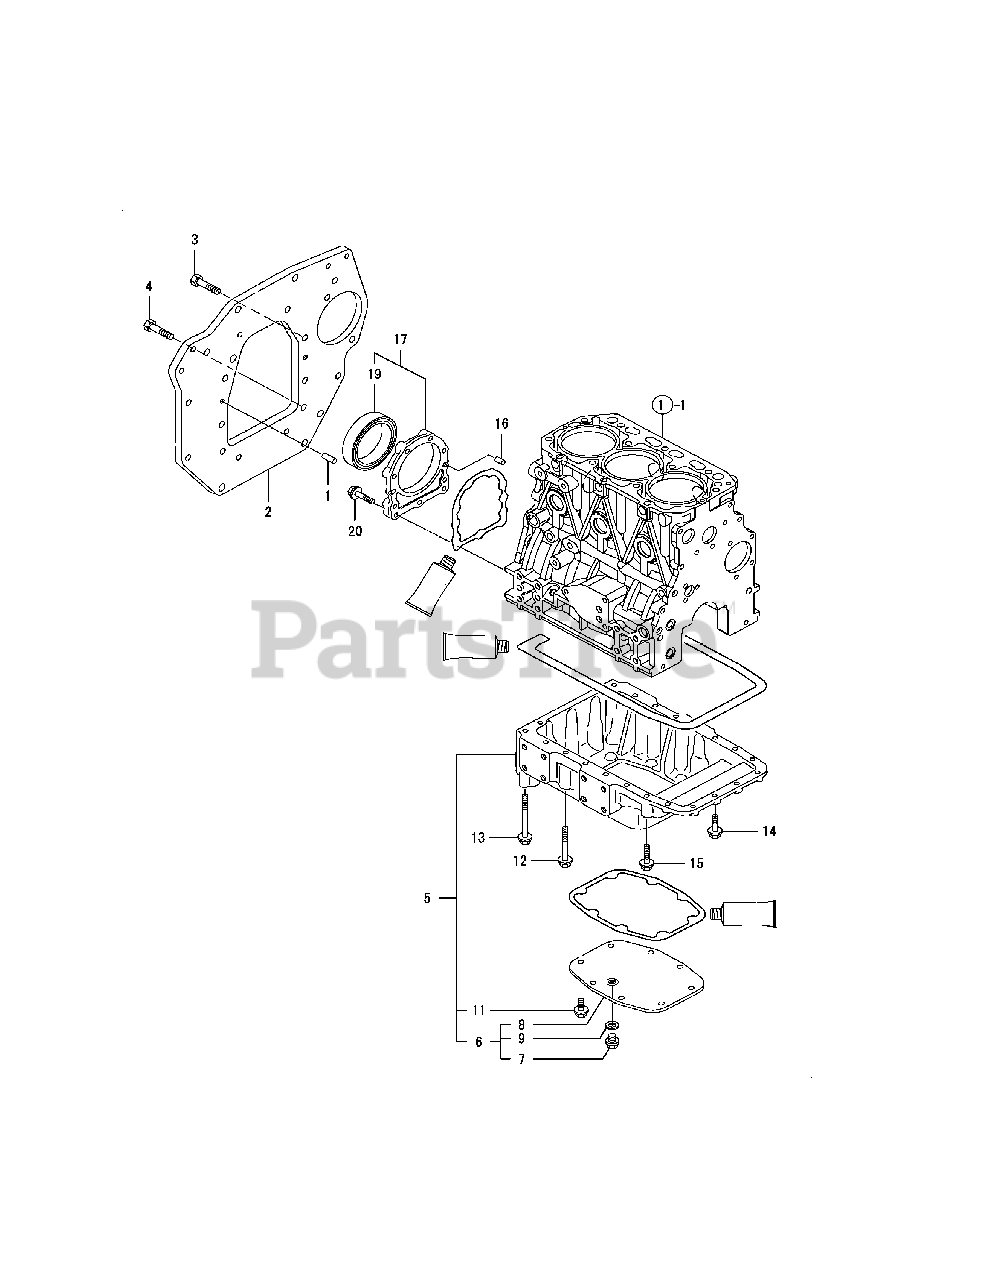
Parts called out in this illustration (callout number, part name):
1	PARALLEL PIN 8X16
2	PLATE, REAR MOUNTING
5	PAN ASSY, ENGINE OIL
6	COVER ASSY, OIL PAN
8	COVER, OIL PAN
9	SEAL WASHER 16S
11	BOLT M 8X 12 PLATED
12	BOLT, M8X85
13	BOLT, M8X120
14	BOLT M 8X 25 PLATED
15	BOLT M 8X 50 PLATED
16	PARALLEL PIN 8X16
17	CASE ASSY, OIL SEAL
20	BOLT M8X30, COLLAR HD
